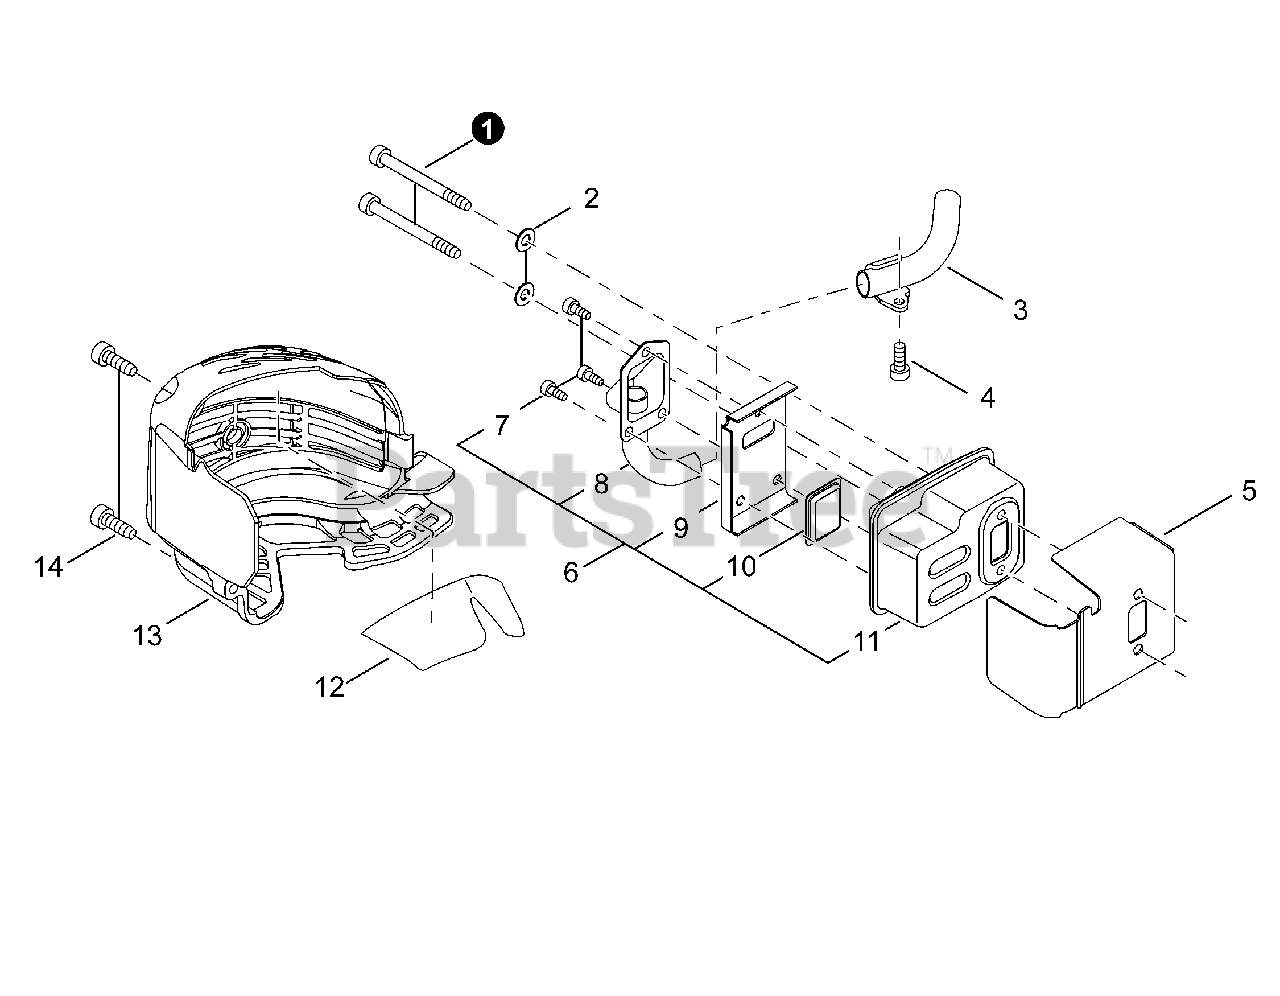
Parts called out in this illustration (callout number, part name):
1	BOLT, TORX 5×55
2	WASHER 5.5×12×0.8
3	GUIDE, EXHAUST
4	BOLT, TORX 5×10
5	HEAT SHIELD, EXHAUST
6	MUFFLER ASSY
7	BOLT, TORX 4×8
8	GUIDE, EXHAUST
9	GASKET, EXHAUST
10	SCREEN, SPARK ARRESTER
11	MUFFLER
12	PLATE, INSULATOR
13	COVER, MUFFLER
14	BOLT, TORX 5×16
